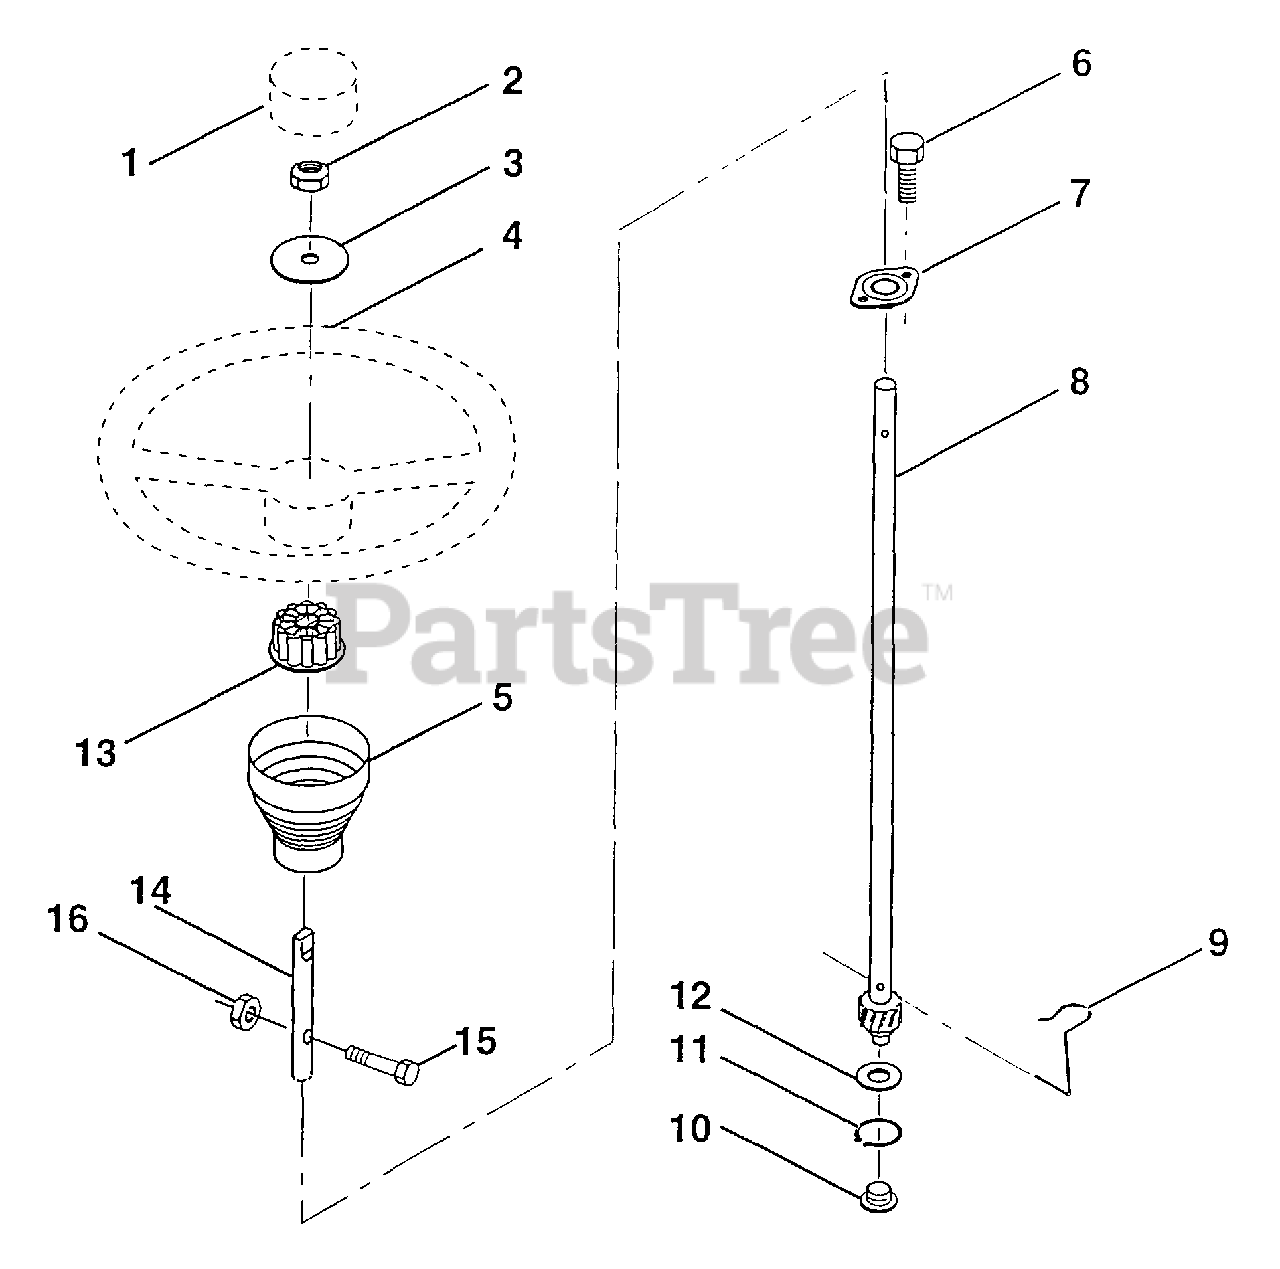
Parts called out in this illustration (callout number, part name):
1	Insert, Wheel, Steering
2	Washer Lock Hevy
3	Washer 12/32 x 2-3/8 x 8 Ga.
4	Wheel, Steering (AYP part number)
5	Sleeve, Steering
6	Screw
7	Bushing, Steering (AYP part number)
8	Shaft, Steering (AYP part number)
9	Clip, Steering
10	Bushing, Lower, Steering
11	Ring, Retaining
12	Washer 21/32 x 1 x 16 Ga.
13	Adaptor, Wheel, Steering
14	Extension Shaft, Steering (AYP part number)
15	Bolt, Fin, Hex 5/16-18 UNC x 1-1/4 (AYP part number)
16	Nut, Lock, Hex W/Ins. 5/16-18 UNC (AYP part number)
17	Bolt Fin Hex 3/8-16 unc x 1
